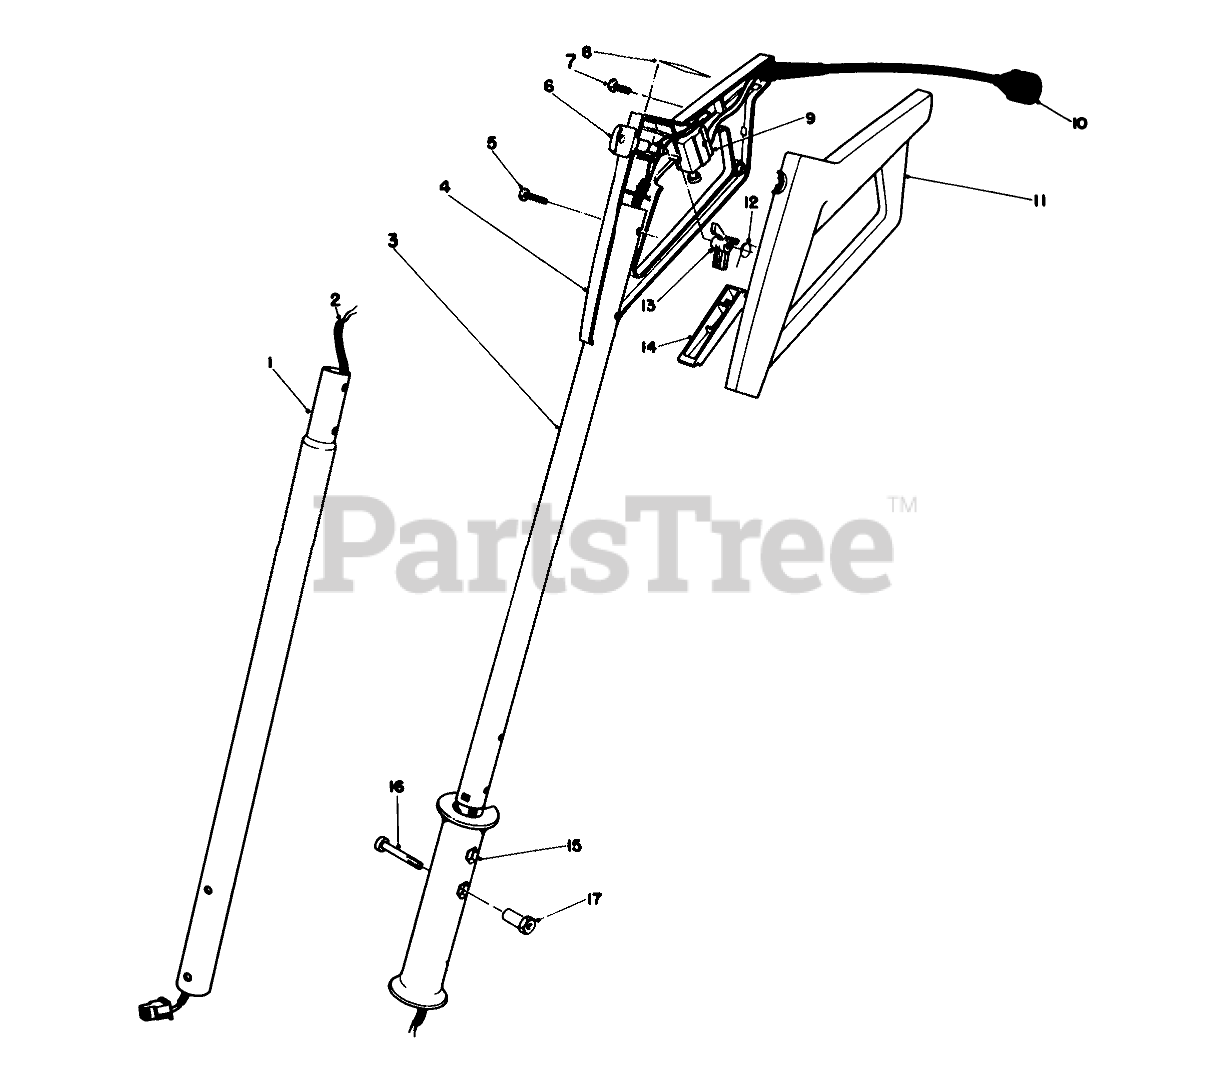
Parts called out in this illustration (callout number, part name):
1	LOWER TUBE, P. SHOVEL
2	Wire Harness
3	Tube-Upper Handle
4	Grip-Control R.H.
5	Screw
7	SCREW-PPH
8	Decal-Control Grip
9	SWITCH-STARTER
10	Cord-Supply
11	Grip-Control L.H.
12	TORSION SPRING
13	LOCKOUT
14	SWITCH BAR,POWER SHOVEL
15	Grip-Handle
16	SPEC PAN HD SCREW
17	SPECIAL HEX NUT
